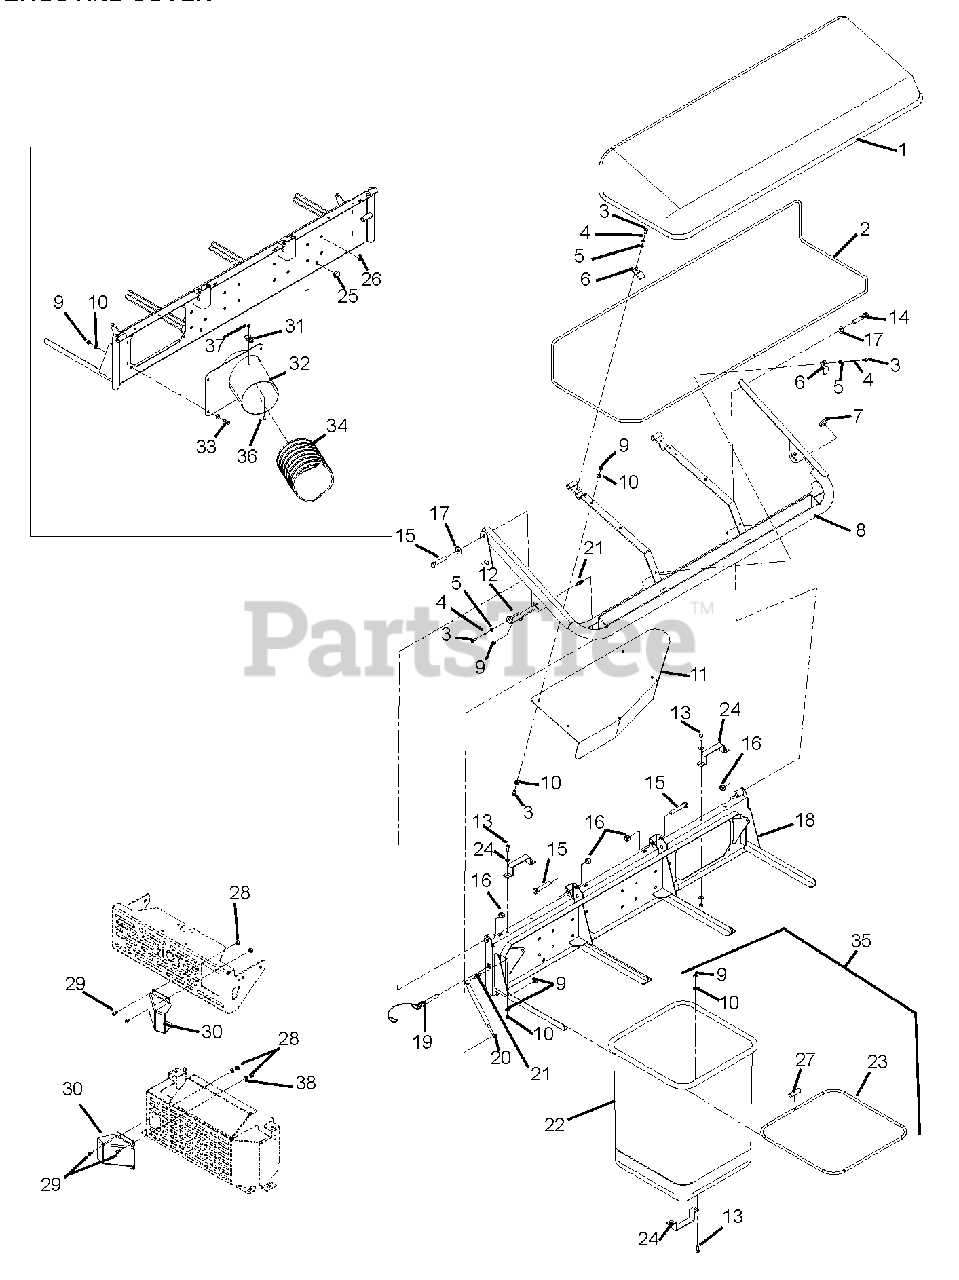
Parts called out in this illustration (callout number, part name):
1	3-Bag Fabric Cover W/J-Strip
2	Air Dome Frame .38 Rod
3	Bolt, Hex .25-20 x .75 Grade 5
4	Washer, Locking .25 x .062
5	Washer, Flat Steel .281 x .62 x .065
6	Bracket, Mount Single Hole
7	Hole Plug, Round
8	Cap Support
9	Nut, .31-18 Nyloc Flange
10	Washer, Flat, Steel .344 x .688 x .065
11	3-Bag Deflector
12	Bracket, Gas Cylinder Mount
13	Bolt, Hex .31-18 x .75 Grade 5
14	Bolt, Hex .50-13 x 2.50 Grade 5
15	Bolt, Hex .50-13 x 3.00 Grade 5
16	Nut, Locking-Nylon .50-13
17	Washer, Flat-Steel .531 x 1.06 x .095 YWZC
18	3-Bag Support Mount
19	Detent Pin W/Lanyard 1/2 x 2-.50
20	Gas Cylinder
21	Ball Stud
22	Cloth Bag
23	Grass Bag Frame
24	Bag Handle
25	Rubber Bumper
26	Hole Plug 7/16
27	Tube Connector
28	Nut, Locking Center .25-20 (200 Series Vertical Shaft)
29	Bolt, Hex .25-20 x .50 Grade 5 (200 Series Vertical Shaft)
30	Deflector, Exhaust
31	Thumb Latch, A-10 Quick Release
32	Inlet Adapter 200 Series
33	Bolt, Hex .31-18 x 1.00 Grade 5
34	Hose, 7 x 45 Goodyear
35	Bag Assembly
36	Screw, Machine 10-24 x .50 Hex Washer Head
37	Nut, Locking Nylon 10-24 with Insert
38	Washer, Flat-steel .312 x .734 x .065
